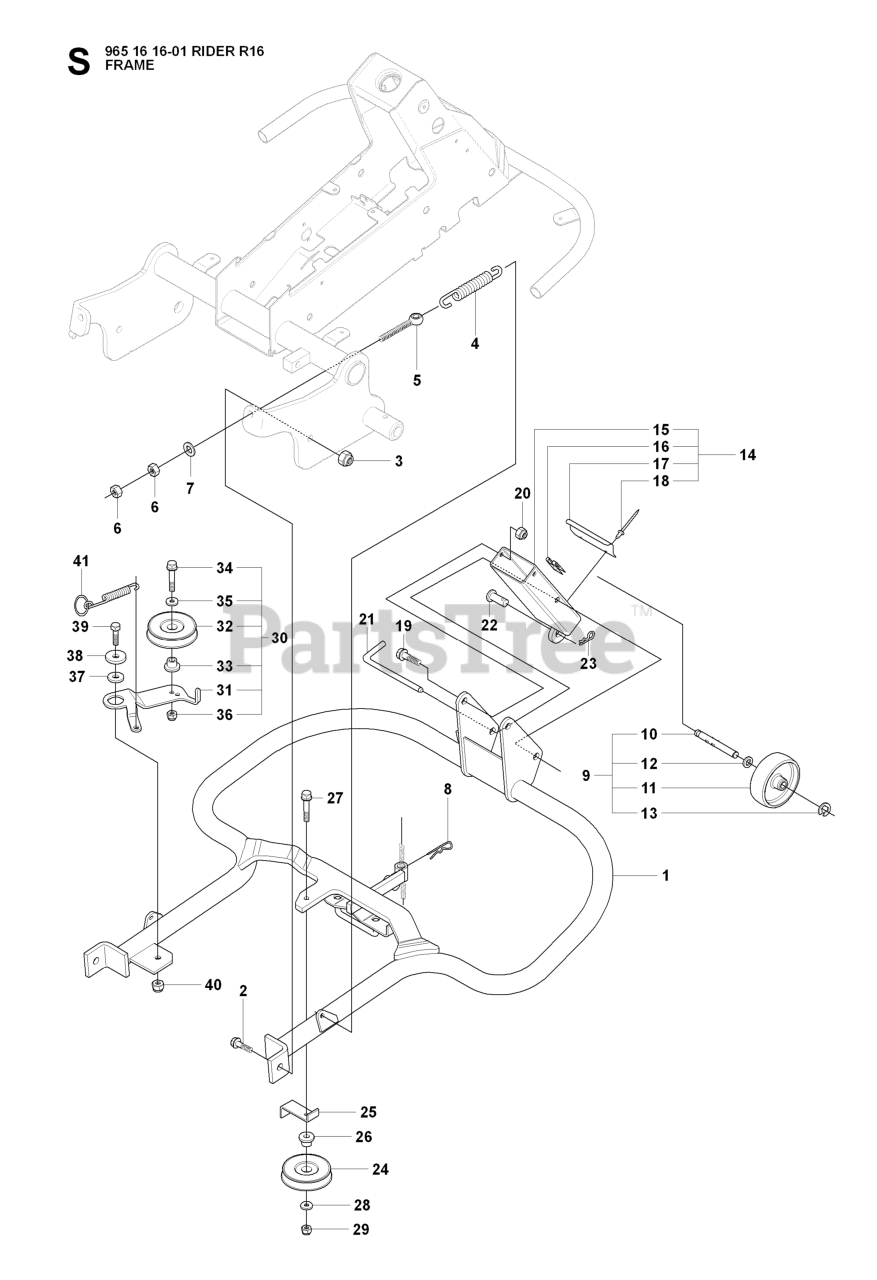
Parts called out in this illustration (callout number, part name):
6	NUT
7	WASHER
9	WHEEL ASSY
13	RETAINING RING
20	LOCKNUT M8
29	LOCKNUT M8
30	BELT TENSIONER ASSY
36	LOCKNUT M8
40	NUT
